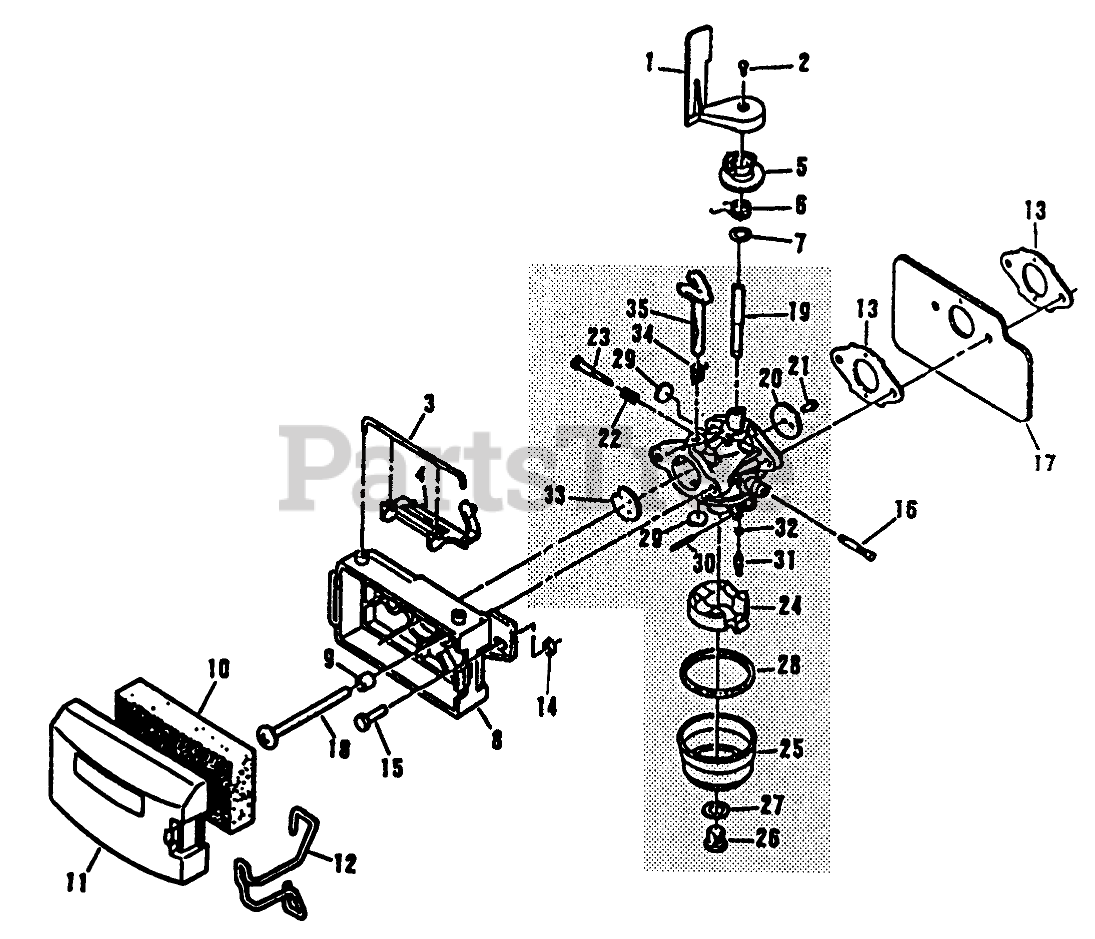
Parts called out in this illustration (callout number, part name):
1	AIR VANE F
2	SCREW F
3	RETAINER
4	LEVER F
5	COLLAR A/VAVE F
6	THROTTLE SPR E
7	WASHER VF
8	BASE,AIR FILT S
9	SPACER
10	ELEMENT-AIR FIL VF
11	Air Filter Cover
12	RETAINER-COVER, FILTER
13	GASKET CARB S
14	Nut
15	SCREW
16	SCREEN FUEL PITTS
17	SHIELD, CARB F
18	SCREW
19	Throttle Shaft
20	Throttle Valve
21	Screw-Throttle Valve
22	Spring-Idle Needle
23	Idle Needle
24	BOWL KIT S
25	Fuel Bowl
26	Screw-Bowl Retainer
27	Bowl Retainer Gasket
28	Fuel Bowl Gasket
29	Plug-Welch
30	Float Shaft
31	Inlet Needle Valve
32	Valve Seat
33	Choke Valve
34	Choke Return Spring
35	Choke Shaft
